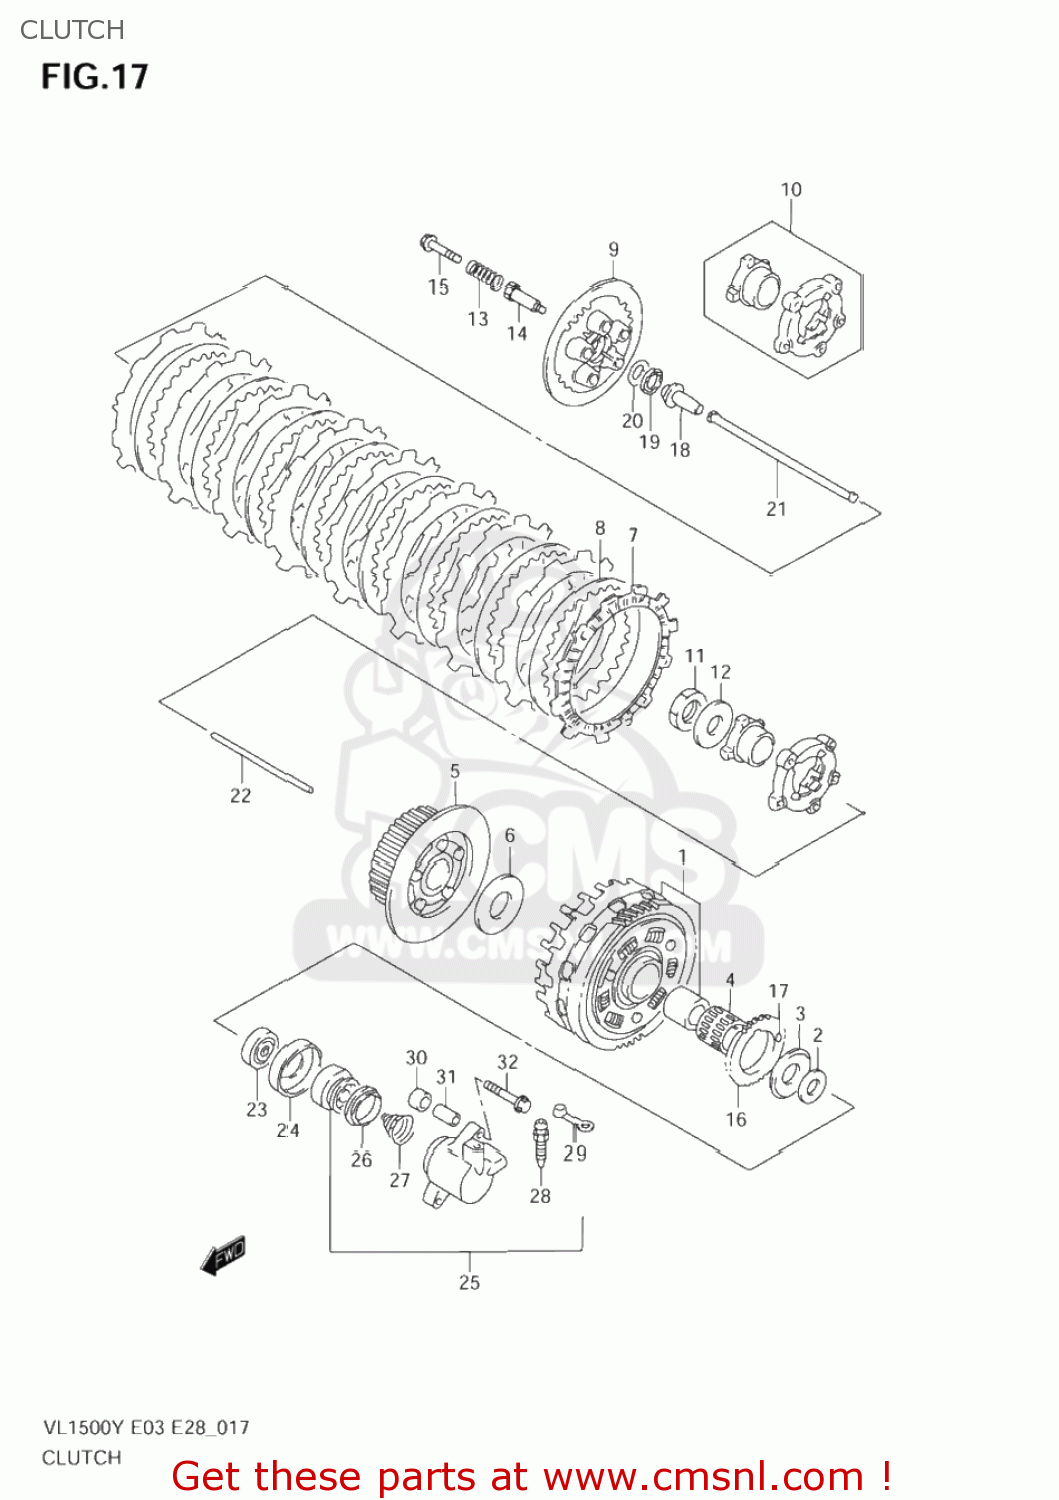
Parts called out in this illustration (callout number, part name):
1	GEAR ASSY,PRI DRIVEN
2	WASHER(25X38X2.5)
3	WASHER(25X54X2.5)
4	BEARING(35X40X35.8)
5	HUB,CLUTCH SLEEVE
6	WASHER(25X50X2.5)
7	PLATE,CLUTCH DRIVE (NAS)
8	PLATE,CLUTCH DRIVEN NO.1 (NAS)
9	DISC,CLUTCH PRESSURE
10	CAM SET,CLUTCH
11	NUT
12	WASHER
13	SPRING,CLUTCH
14	BOLT,CLUTCH SPRING SUPPORT
15	BOLT,CLUTCH SPRING
16	GEAR,OIL PUMP DRIVE
17	PIN(6X6)
18	PIECE,CLUTCH PUSH
19	BEARING(15X28X2)
20	WASHER(15.5X28X1)
21	ROD,CLUTCH PUSH,R
22	ROD,CLUTCH PUSH,L
23	SEAL,OIL(6X34X11)
24	RETAINER,CL PUSH ROD OIL SEAL
25	CYLINDER,CLUTCH RELEASE
26	CUP
27	SPRING
28	BLEEDER
29	CAP,BLEEDER
30	SPACER(9X16X11)
31	PIN(6.4X9X23)
32	BOLT
